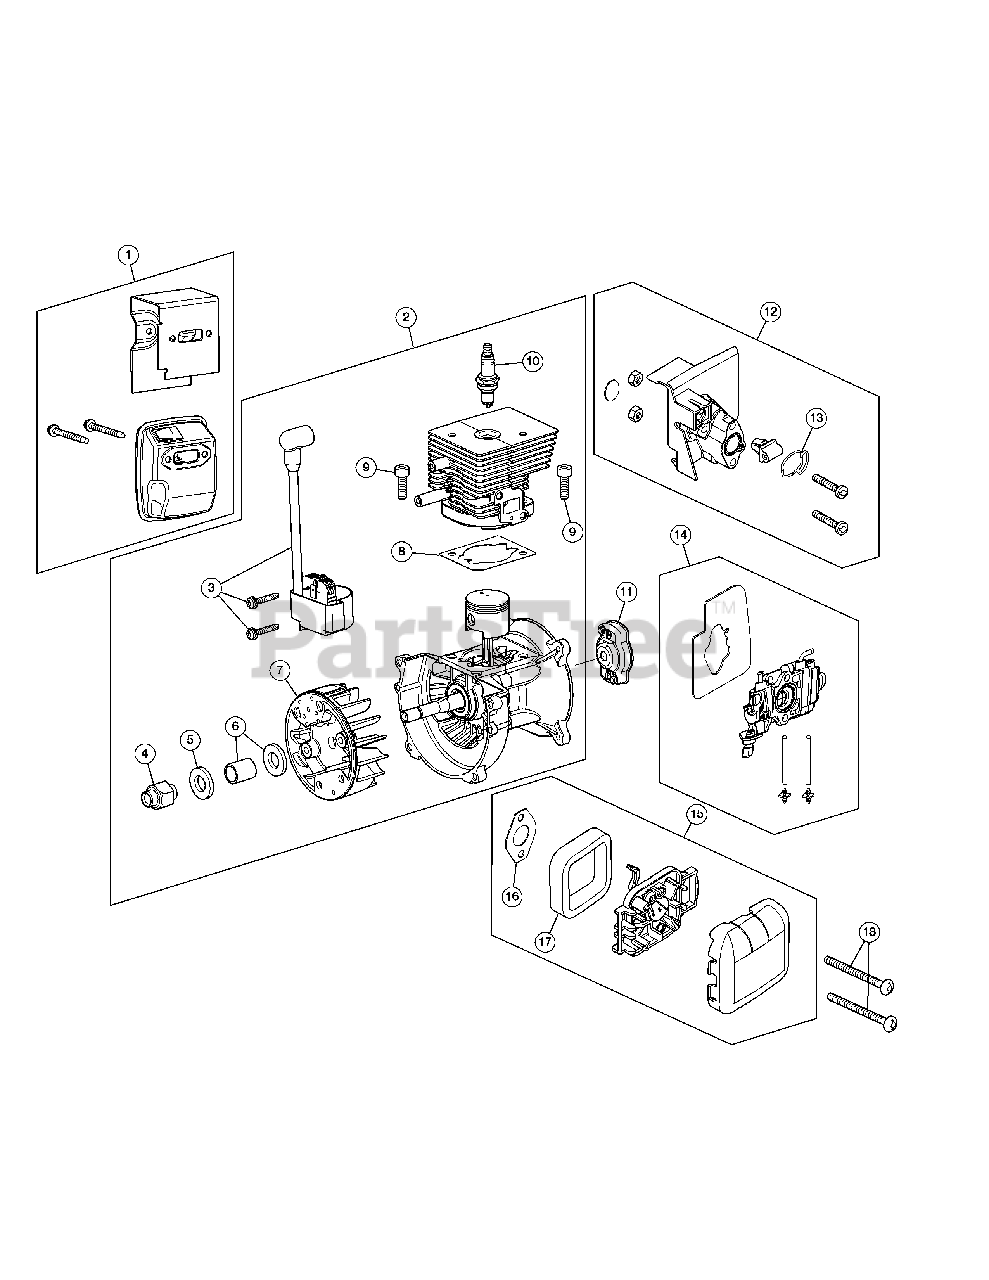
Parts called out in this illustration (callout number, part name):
1	Muffler Assembly
2	Shortblock Assembly (Incl. 3 - 10)
3	Module Assembly
4	Flywheel Adaptor
5	Washer
6	Bushing
7	Flywheel Assembly
8	Cylinder Gasket
10	Spark Plug
11	Pawl Assembly
12	Insulator Assembly (Incl. 13)
13	Insulator O-Ring
14	Carburetor Assembly
15	Air Cleaner Assembly (Incl. 16 and 17)
16	Carburetor Gasket
17	Air Filter
18	Air Cleaner Screw
